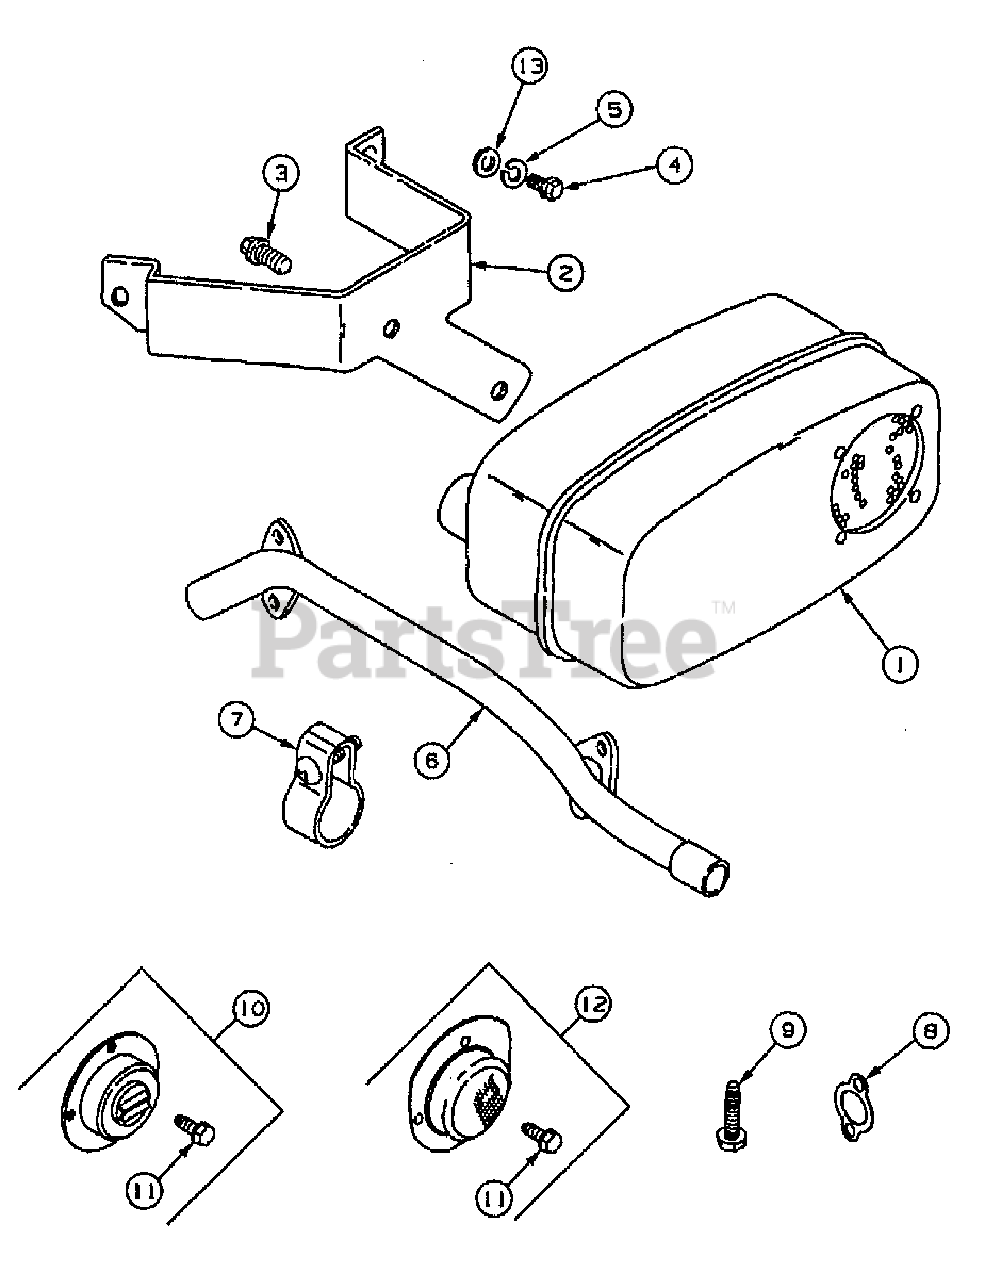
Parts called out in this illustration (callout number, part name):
1	Muffler
2	Bracket, Muffler
3	Screw, Hex Wash Hd Tap 1/4-20 x .50
4	Screw, Hex Cap M6-1.0 x 20mm Gr 10.9
5	Washer, Lock 1/4
6	Manifold, Exhaust
7	Camp, Muffler
8	Gasket, Exhaust Manifold
9	Screw, Sem
10	Deflector, Exhaust
11	Screw, Hex Wash Hd Tap 8-32 x 3/8
12	Arrestor, Spark
13	Washer, Flat, .281 x .75 x .105 Thk
